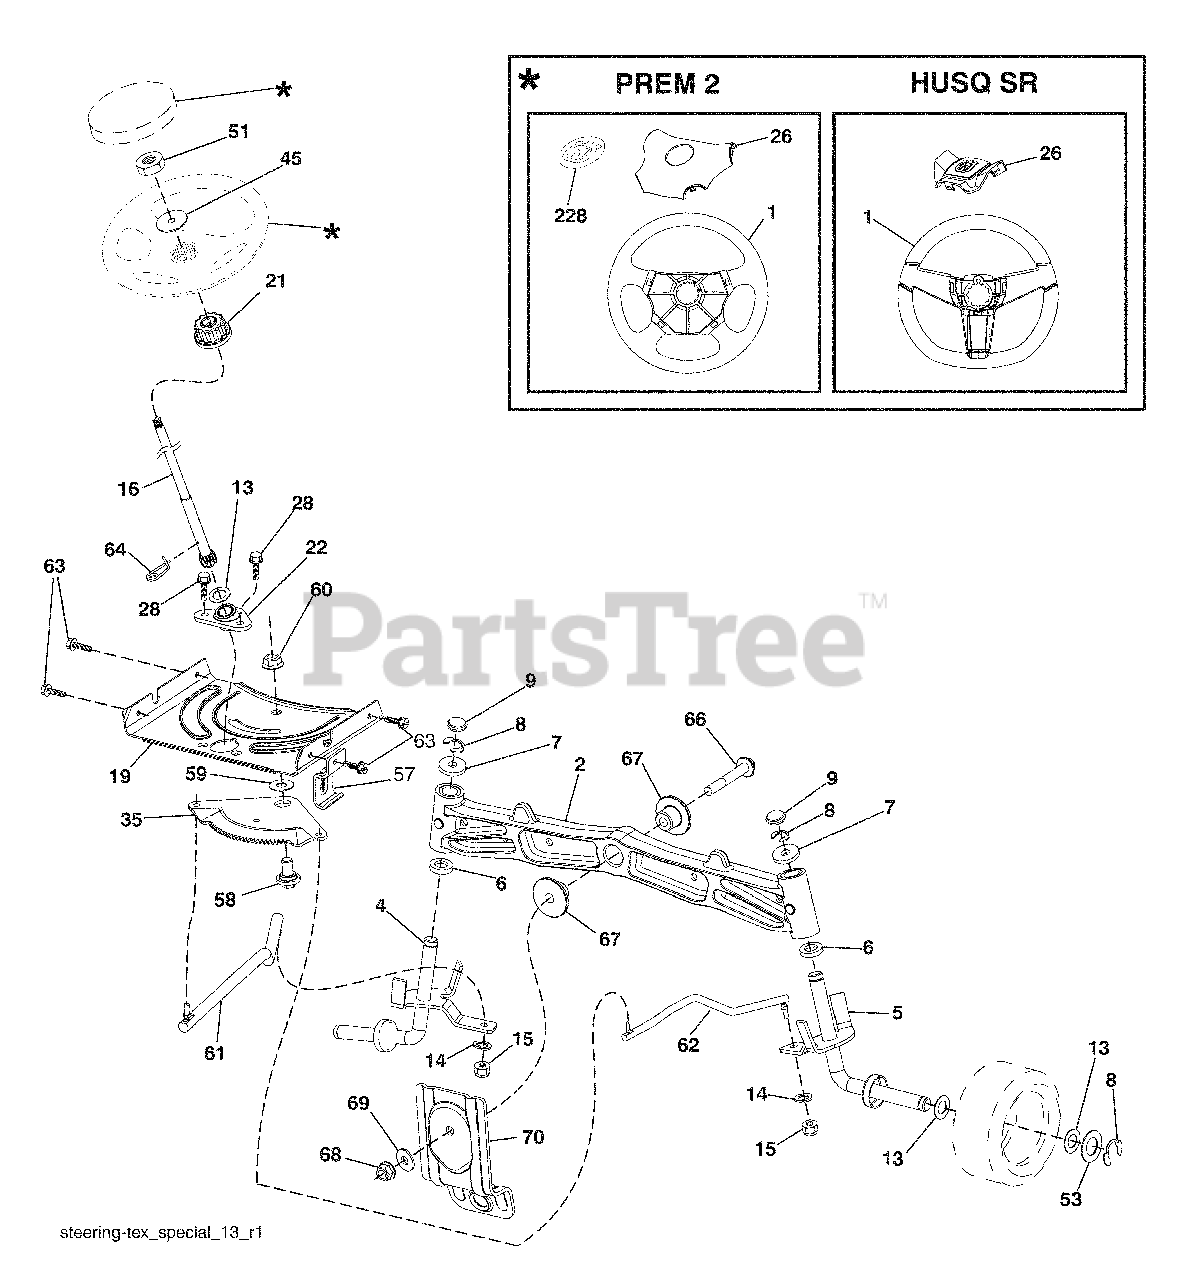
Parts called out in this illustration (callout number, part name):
1	Wheel, Steering
2	Axle Asm., Front
4	Spindle Asm., LH
5	Spindle Asm., RH
6	Bearing, Race Thrust Harden
7	Washer 25/32 x 1-5/8 x 16 Ga.
8	Ring, Klip #T5304-75
9	Cap, Spindle
13	Washer 25/32 x 1-1/4 x 16 Ga.
14	Washer, Lock Hvy Hlcl Spr 3/8
15	Nut, Crown Lock 3/8-24 unf
16	Shaft Steering
19	Plate Steering
21	Adapter, Wheel Steering
22	Bushing, Strg. Blk
26	Insert, Wheel Steering
28	Screw 3/8-16 x 3/4
35	Gear, Sector Plate
45	Washer 9/16 ID x 2-3/8 OD 12 Ga.
51	Nut Hex Jam Toplock 1/2-20 unf
53	Washer Hardened .793 x 1.637 x .060
57	Bracket Upstop
58	Bolt Shoulder Sector Pivot CFM
59	Washer Thrust Sector Steering
60	Nut Flange Lock 5/8-11
61	Draglink LH
62	Draglink, RH
63	Screw 5/16-18 x 3/4
64	Retainer Clip Spring Steering
66	Bolt Hex Fghd 7/16-14 x 3 Serr
67	Bushing PM Front Axle
68	Nut Lock Flange 7/16-14 Gr. 5
69	Washer 1.5 x .505 x .118
70	Bracket Deck Susp. Front
228	Decal Wheel Steering
